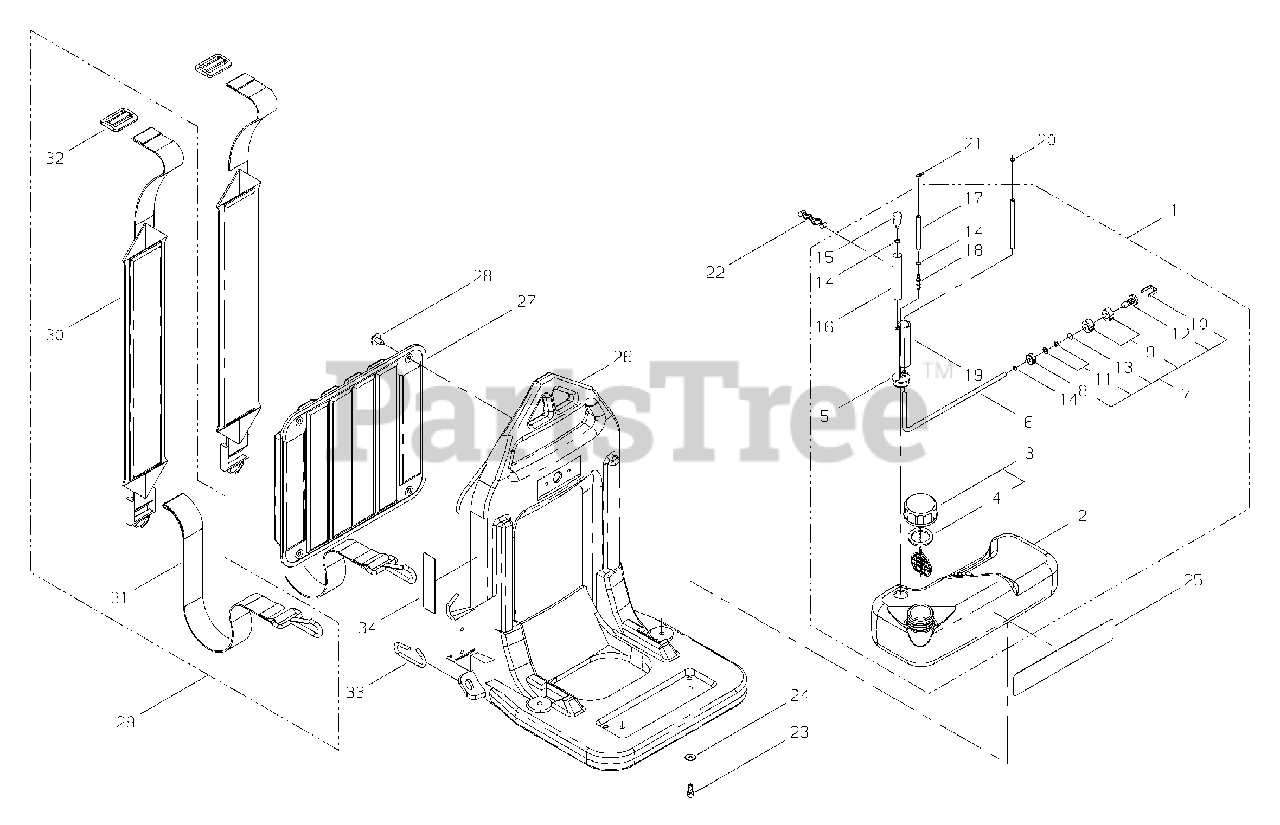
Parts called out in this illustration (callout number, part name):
1	FUEL TANK ASSY
2	TANK, FUEL
3	CAP ASSY
4	GASKET, CAP
5	PIPE ASSY
6	PIPE - FUEL
7	FILTER, FUEL
8	WEIGHT, FUEL FILTER
9	FILTER, FUEL
10	CLIP, FILTER
11	SCREEN, FILTER
12	CASE, FILTER
13	RING, RETAINING
14	RING, RETAINING - 6
15	VENT, FUEL TANK
16	TUBE
17	PIPE
18	CONNECTOR, PIPE
19	SLEEVE X12 X X11 X L70
20	RING, RETAINING - 6
21	CLIP - SPRING
22	CLIP
23	SCREW - 5X14
24	COLLAR
25	LABEL - MODEL
26	FRAME
27	PAD
28	CLIP
29	HARNESS ASSY
30	STRAP, BACKPACK
31	STRAP
32	BUCKLE
33	HOOK, SPRING
34	LABEL - CAUTION
